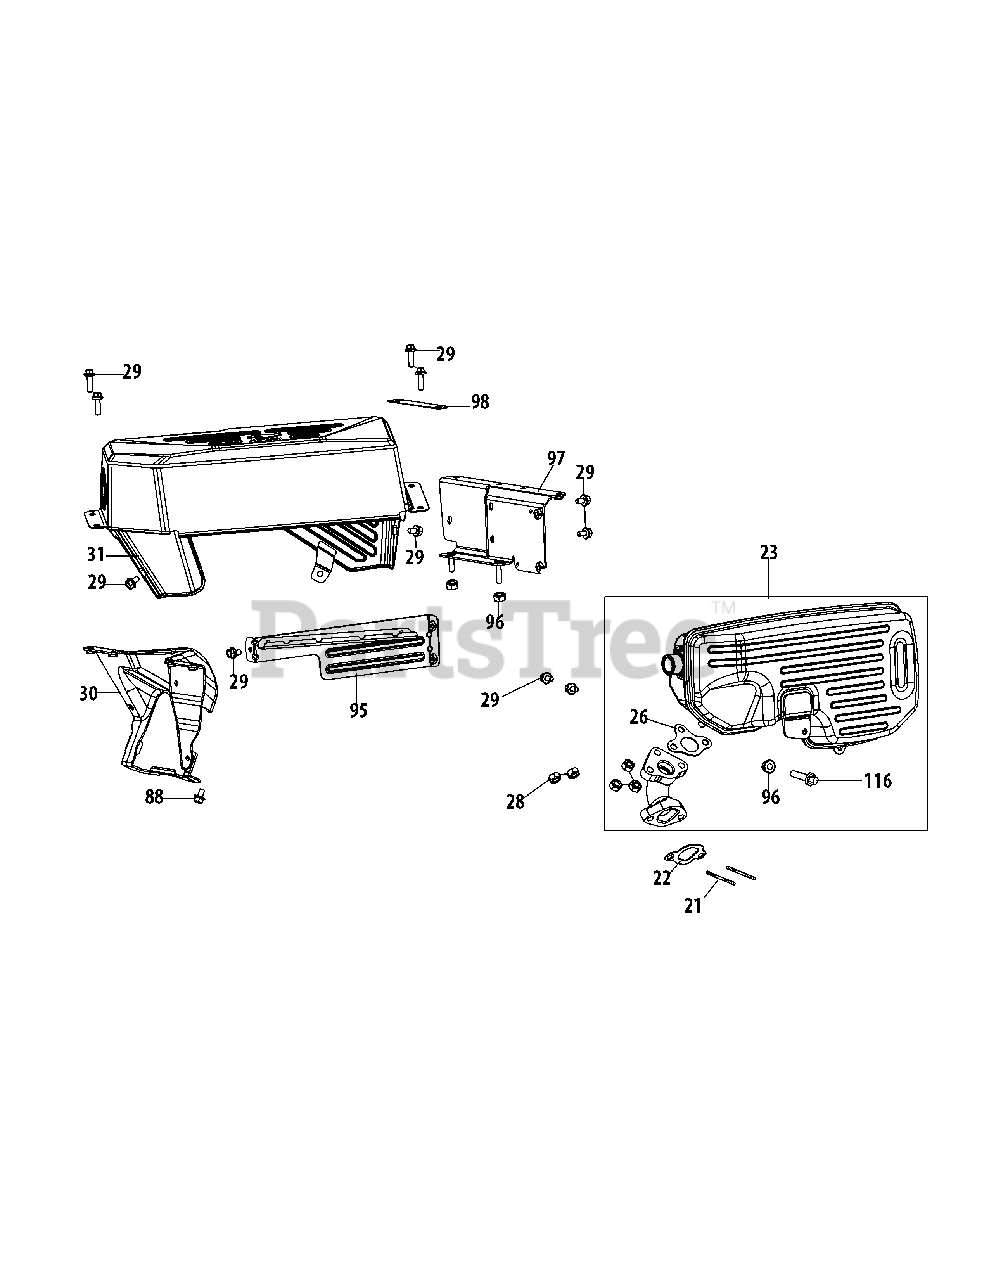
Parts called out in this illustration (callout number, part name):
21	Stud M8×36
22	Muffler Gasket
23	Muffler Assembly
26	Gasket, Muffler
28	Nut M8
29	Bolt M6×12
30	Front Bracket, Fuel Tank
31	Muffler Guard
88	Bolt M6×16
95	Fuel Tank Insulator
96	Flange Nut M6
97	Fuel Tank Bracket
98	Muffler Guard Connection Plate
116	Bolt M6×20
